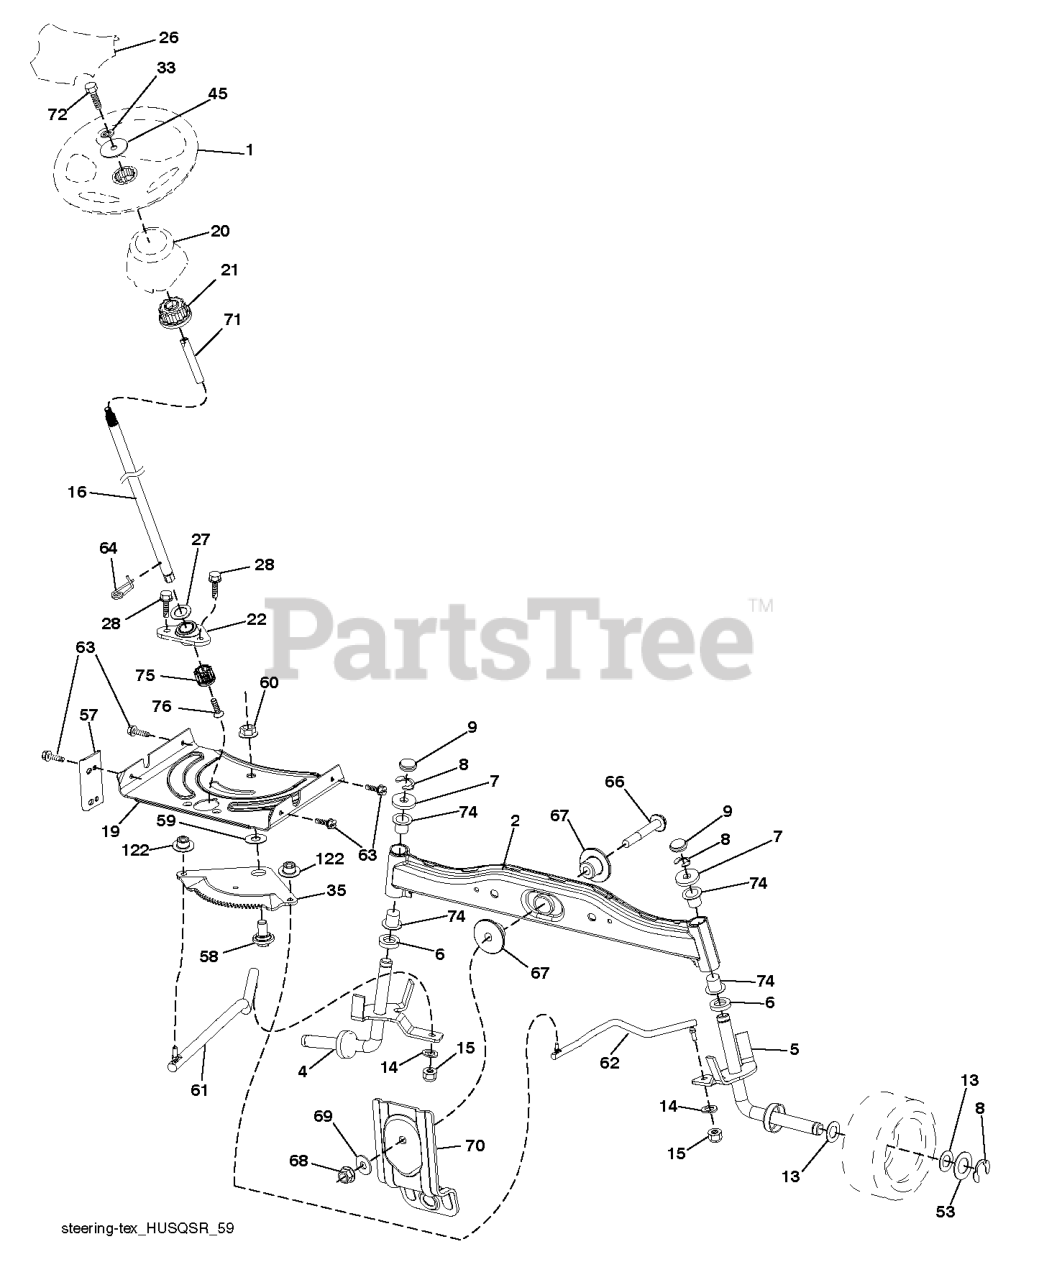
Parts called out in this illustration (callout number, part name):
1	SERVICE KIT KIT.SVC.WELDMENT.5
6	COVER 54 CLEARCUT, LH MANDREL,
7	COVER 54 CLEARCUT RH MANDREL G
8	BOLT.WASHER.ASM.7/16-2
11	BLADE CC54 PZ STYLE HI LIFT BL
14	MANDREL ASM, CAST IRON
20	SPACER.IDLER.PULLY.HUB
23	SCREW.7/16-14 X 2.125.WASHER
24	CAP-SLEEVE LT
25	SPRING.42.FCS.DEFLECTOR
26	NUT PUSH M
27	DEFLECTOR ASSY 54 CLEARCUT RES
28	GSPW Bolts
31	WASHER.SPACER.MANDREL
32	PULLEY/MANDREL
36	GSPW Hardware
37	SHOULDER BOLT 5/16-18TT
41	BOLT.HEX.WASHR.HED.313-18X1.19
43	ARM IDLER ARM, CLEARCUT 54 BLA
46	SCREW.1/4-20X5/8
47	BELT CLEARCUT 54, TRACTOR DECK
49	NUT LOCK FLG 3/8-16 UNC
51	ROLLER, GAUGE .635 BORN
52	PULLEY.IDLER.2006
54	NUT 1/2-13 HEX FLANGE NYLOK CL
63	PIN.COTTER.5/16.BOW TI
66	BUMPER ASSY 54 CLEARCUT TRIM S
98	SPRING.EXTN.42.FCS.TR.DECK.DRV
117	WHEEL.GAUGE.RALLY
187	STUD.W/"D"ANTI-ROTATION
189	ARM.RFIXED.MOWER.SUSPNSIONX431
190	BOLT.SHOULDER
192	KEEPER.BELT.IDLER.54"T
242	PORT.WASHOUT
